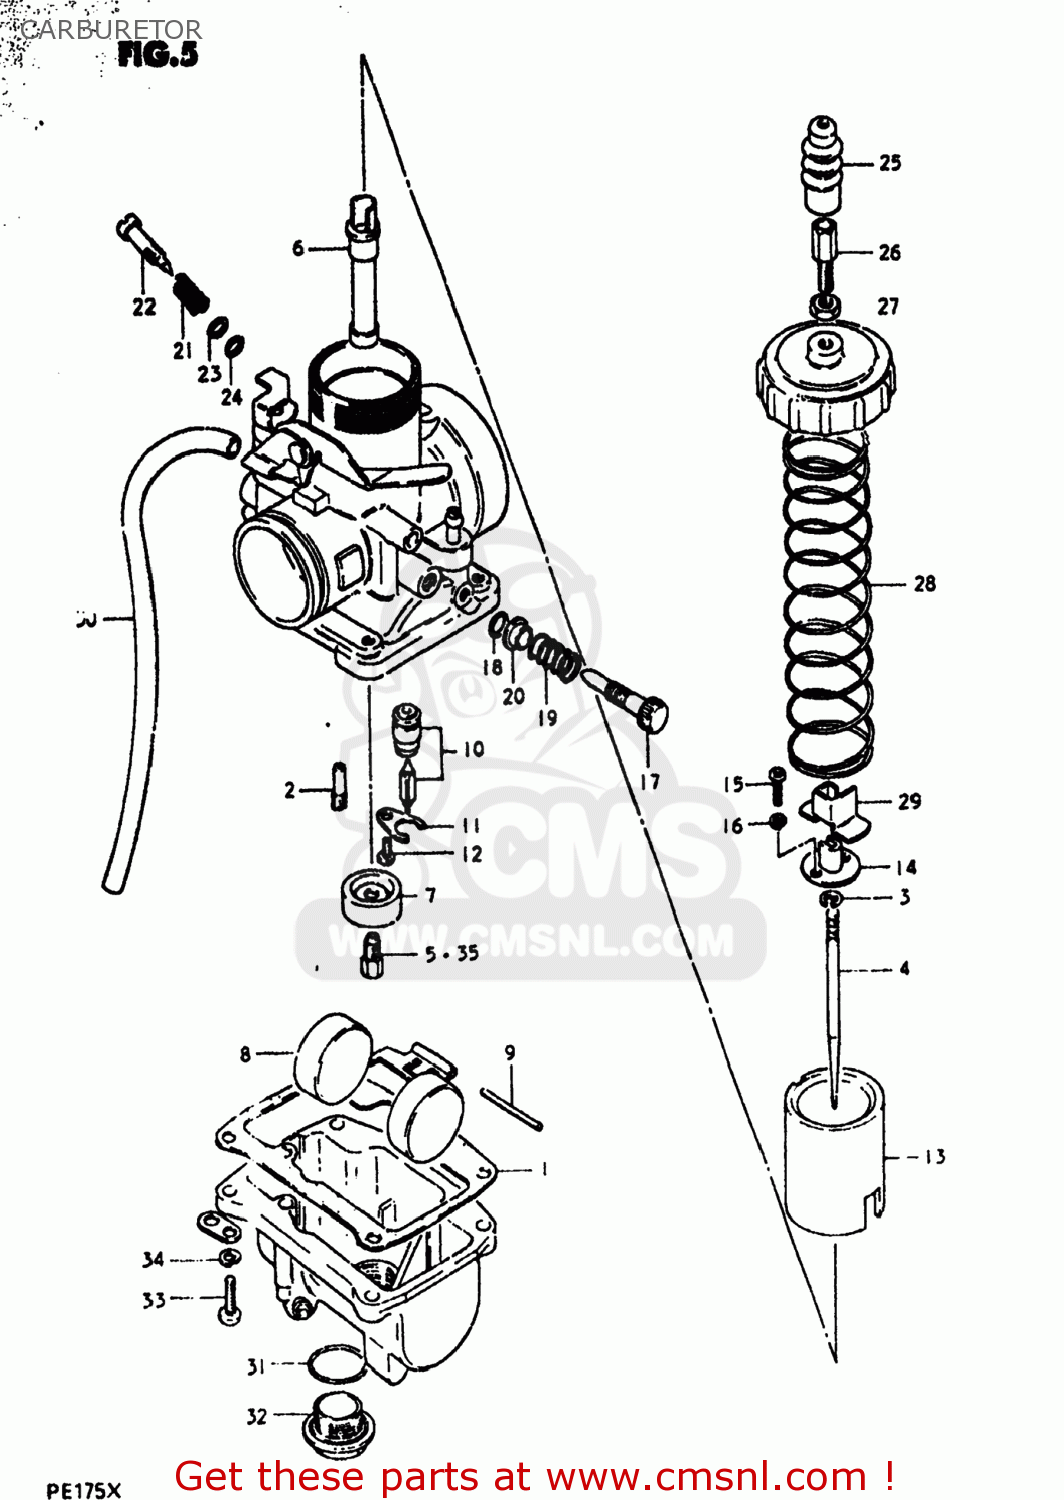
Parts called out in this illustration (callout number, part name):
0	CARBURETOR ASSEMBLY
1	GASKET,FLOAT CAHMBER (NAS)
2	JET
3	CLIP
4	NEEDLE,JET
5	JET
6	JET,NEEDLE
7	RING,MAIN JET FIXING
8	FLOAT
9	PIN,FLOAT
10	VALVE ASSEMBLY,NEEDLE
11	PLATE
12	SCREW
13	VALVE,THROTTLE
14	CONNECTOR
15	SCREW
16	LOCK WASHER
17	SCREW,THROTTLE STOP
18	O-RING
19	SPRING,THROTTLE STOP
20	COVER
21	SPRING
22	SCREW,PILOT AIR
23	WASHER,PILOT AIR SCREW
24	O RING
25	CAP,CABLE ADJUSTER
26	ADJUSTER,CABLE
27	NUT
28	SPRING,THROTTLE VALVE RETURN
29	COVER,HOLDER
30	HOSE
31	O-RING
32	PLUG
33	SCREW
34	LOCK WASHER
35	JET
